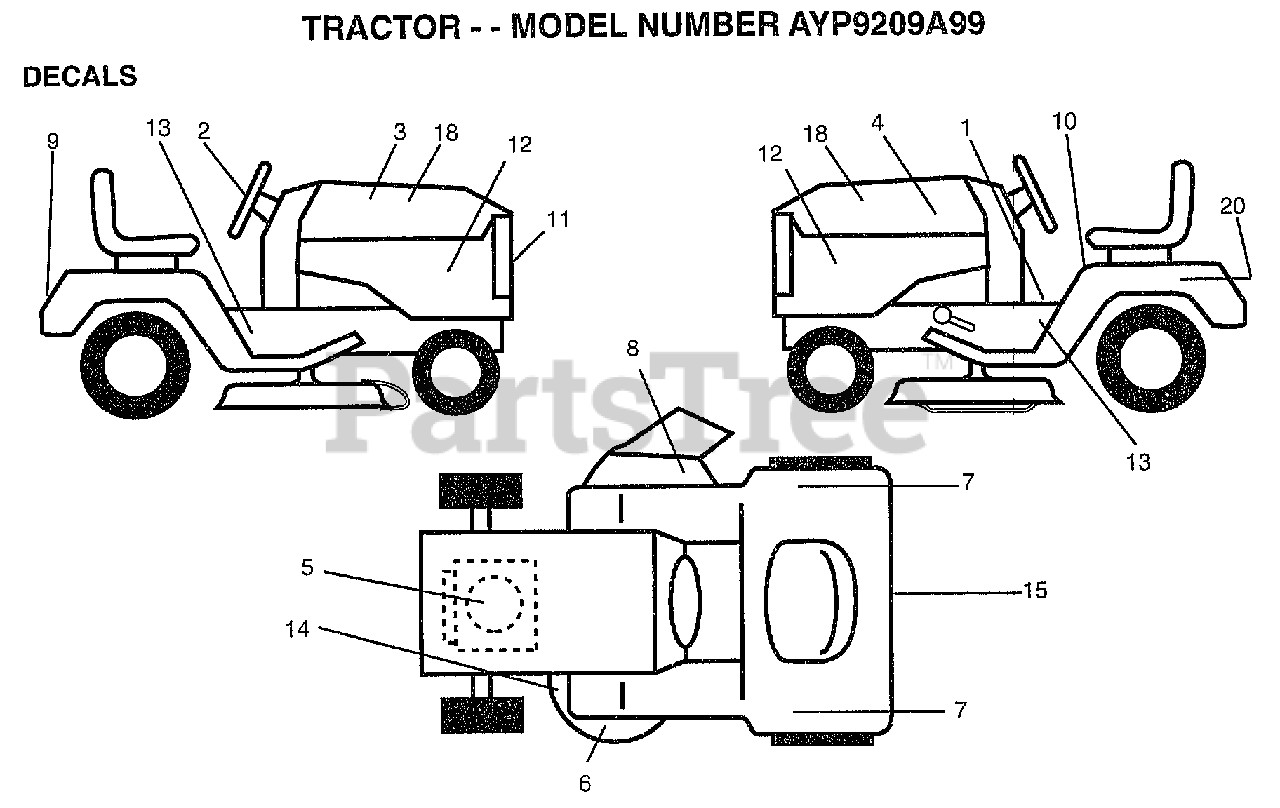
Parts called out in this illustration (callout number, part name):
1	"DEAL-OPER,INST."
2	DECAL.STRNG.WHL
3	DECAL.HOOD.RH.
4	DECAL.HOOD.LH
5	DECAL .B&S.20HP
6	DECAL DECK MULCH
7	DECAL.FENDER.AUTO
8	DECAL DECK WIZ +
10	"DECAL DANGER,FEND"
11	DECAL, LENS LOGO
12	DECAL.PANEL.SIDE
13	DECAL, CHASSIS
15	DECAL DRAWBAR LH
18	NAMEPLATE.HD.WIZA
20	DECAL.BATRY.3-3908
